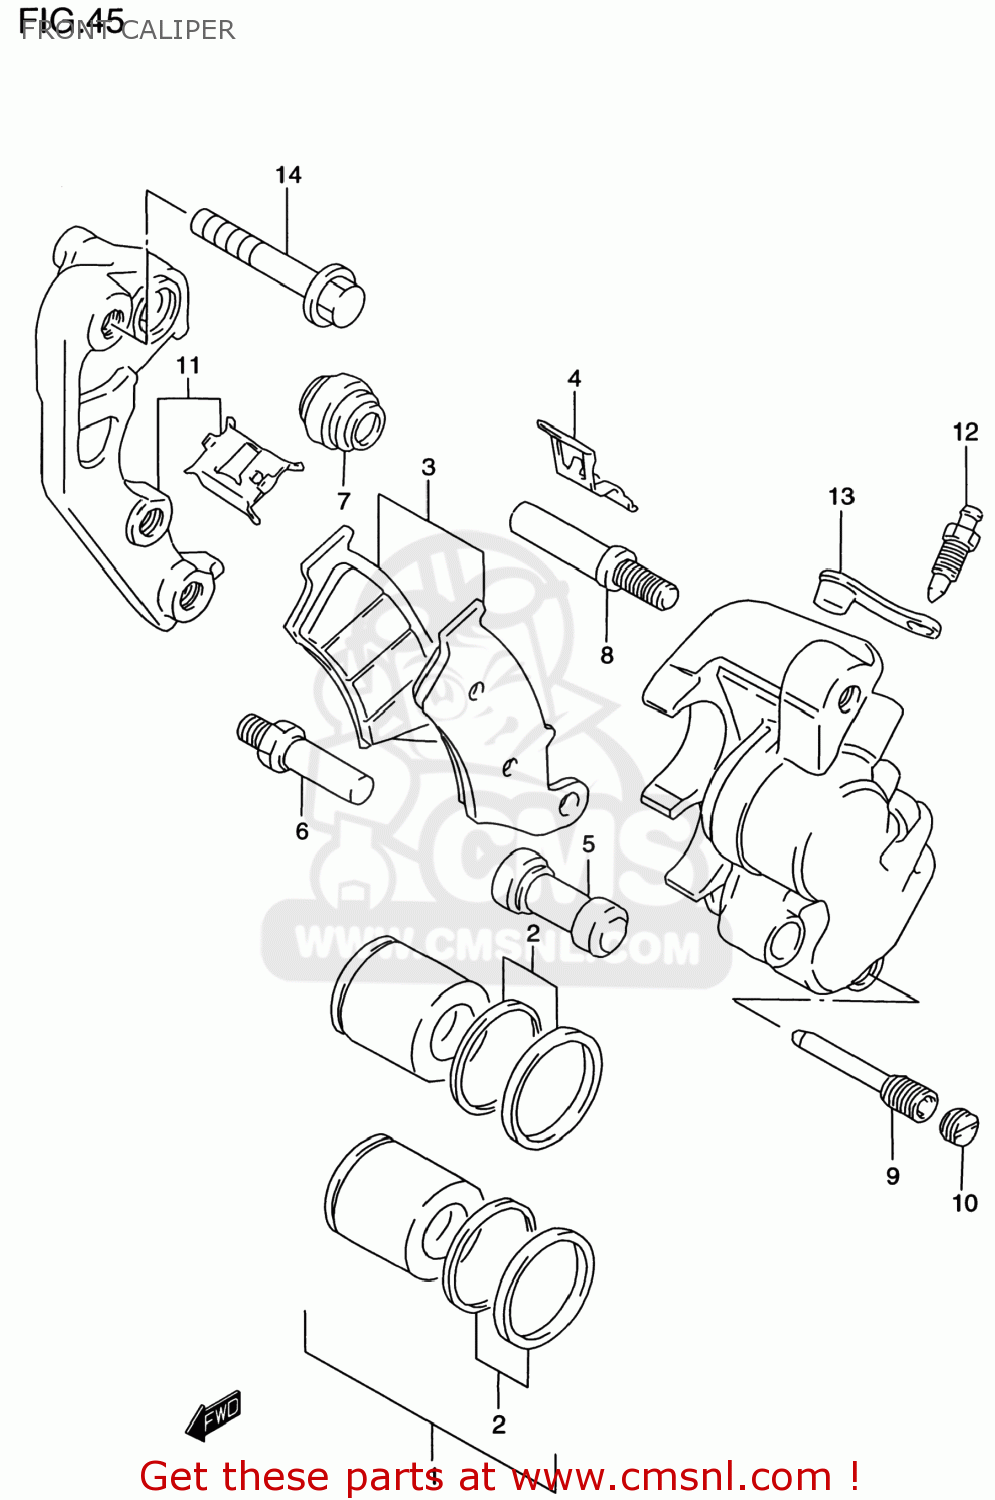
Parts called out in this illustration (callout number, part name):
1	PISTON SET
2	SEAL SET,PISTON
3	PAD SET (NAS)
4	SPRING,PAD
5	BOOT
6	BOLT
7	BOOT
8	PIN
9	PIN,HANGER
10	PLUG,PIN
11	BRACKET
12	BLEEDER
13	CAP,BLEEDER
14	BOLT(8X40)
